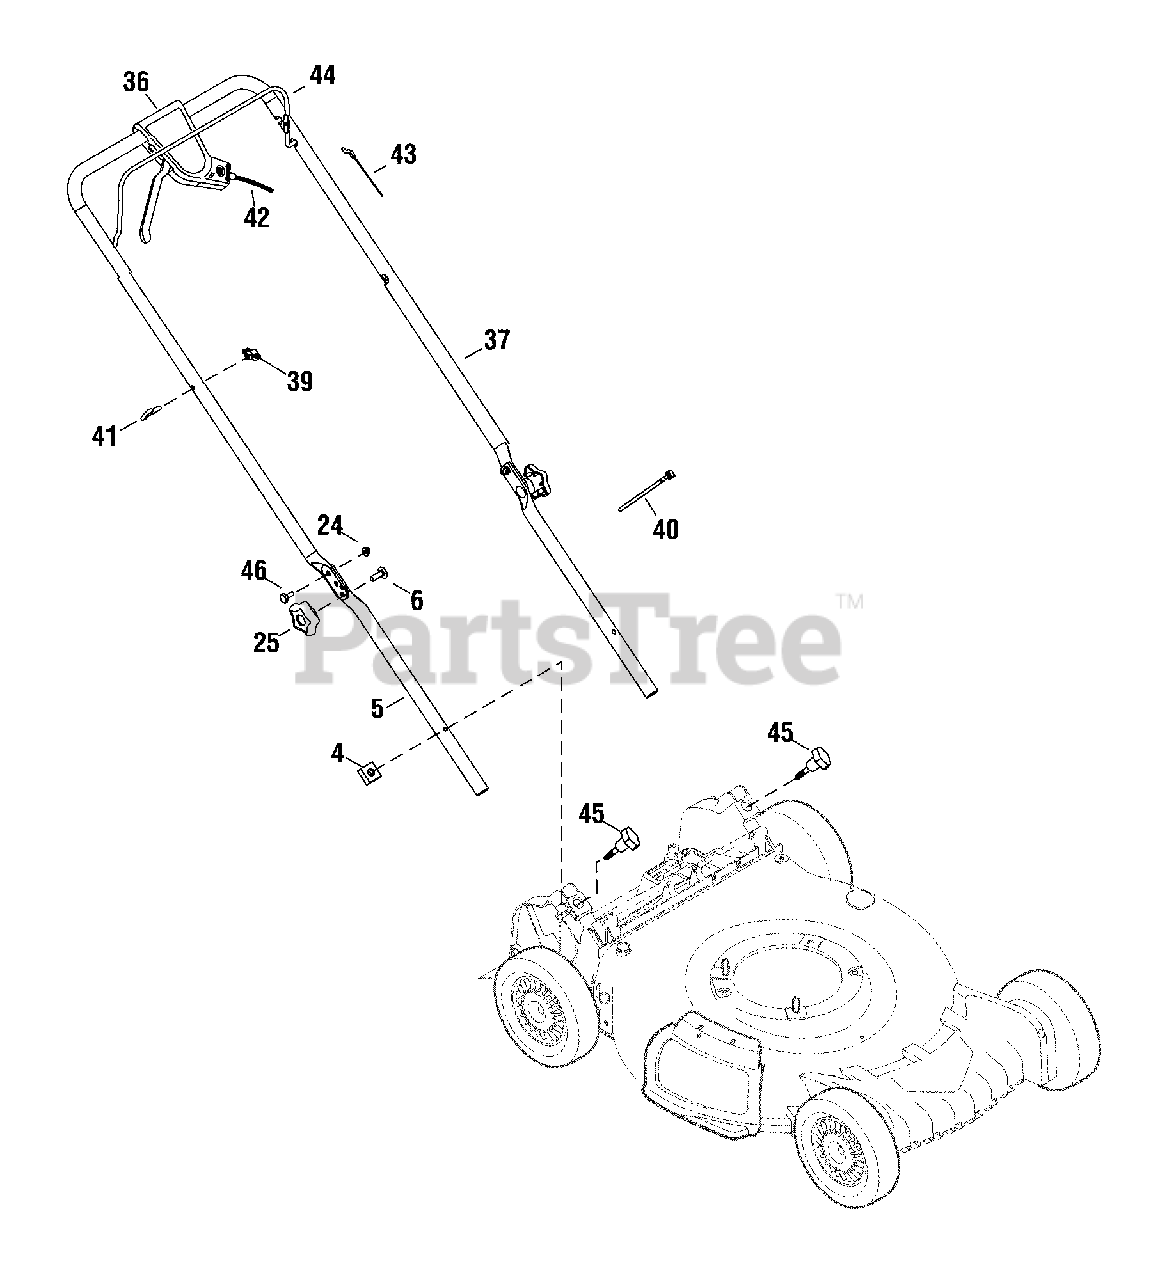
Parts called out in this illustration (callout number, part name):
4	NUT, Square, 1/4-20
5	HANDLE, Lower
6	BOLT, Carriage, 5/16-18 x 1, GR5
24	NUT, Nylock Flanged, 1/4-20
25	KNOB, Wing, 5/16-18
36	ASSEMBLY, Control Lever
37	HANDLE, Upper
39	KNOB, 1/4-20
40	TIE, Self Lock
41	GUIDE, Rope
42	CABLE, Control, Variable Speed
43	CABLE, OPC Engine Brake
44	BAIL, Blade Control
45	NUT, Wing
46	BOLT, Shoulder, 1/4-20
